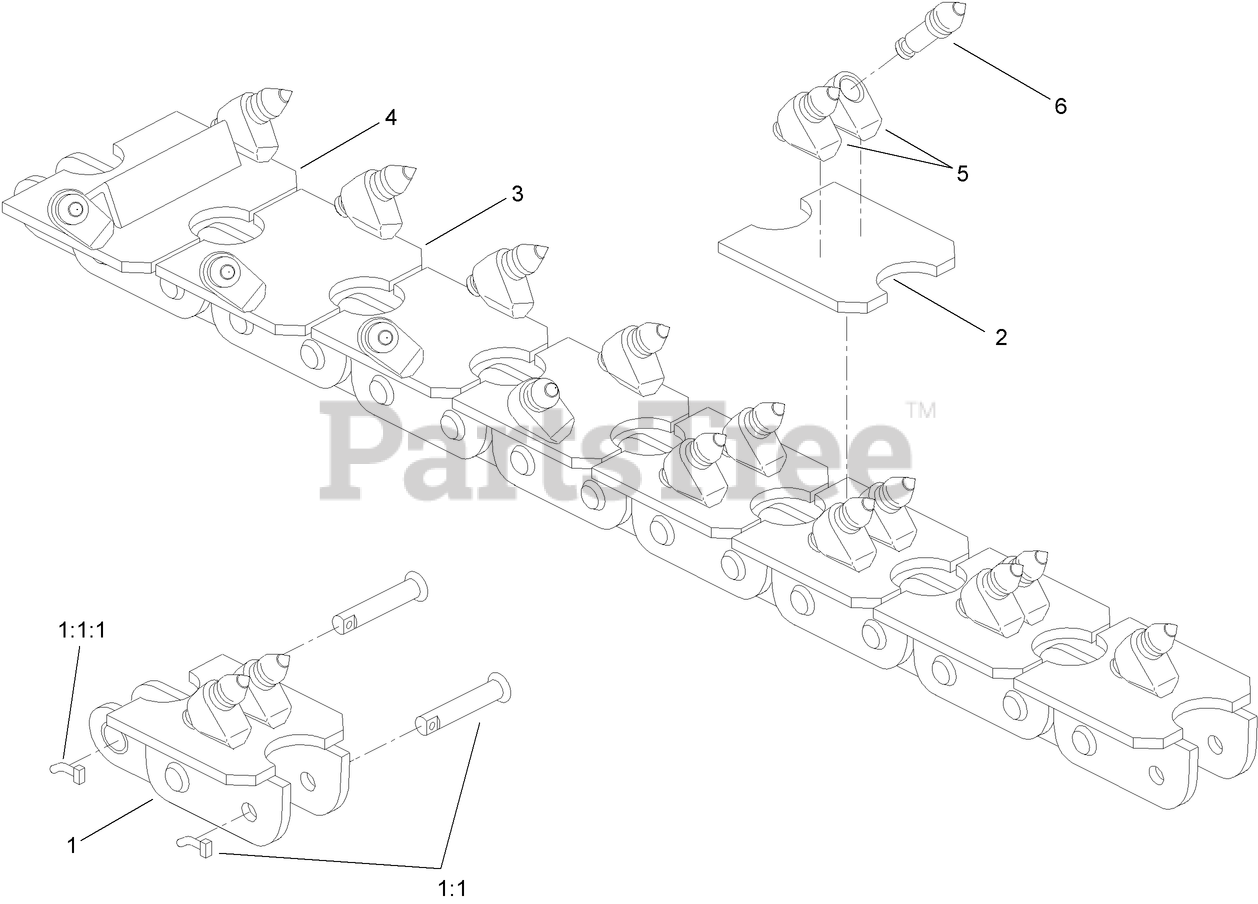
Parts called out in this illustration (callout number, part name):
1	CHAIN REPAIR LINK ASM
1:1	NOTCHED PIN AND KEEPER ASM
1:1:1	PIN-KEEPER
2	PLATE-H, WELD-ON (4 INCH)
3	PLATE-H, WELD-ON (5 INCH)
4	PLATE-H, WELD-ON (6 INCH)
5	HOLDER-BIT, WELD-ON
6	BIT-REAR RETAINER, CARBIDE INSERT
